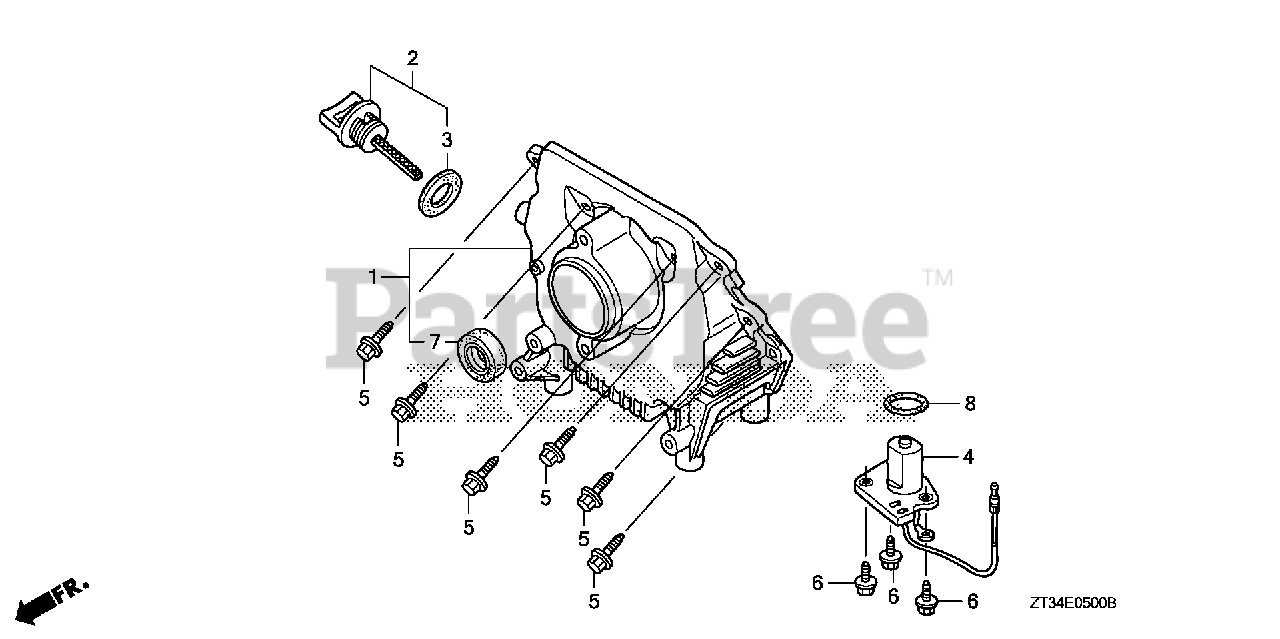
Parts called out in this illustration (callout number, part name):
1	CASE ASSY., OIL
2	CAP ASSY., OIL FILLER
3	GASKET, OIL FILLER CAP
4	SWITCH ASSY., OIL LEVEL
5	BOLT, FLANGE (5X23)
6	BOLT, FLANGE (5X14)
7	OIL SEAL (17X27X5) (KOYO)
8	O-RING (34.6X2.5)
